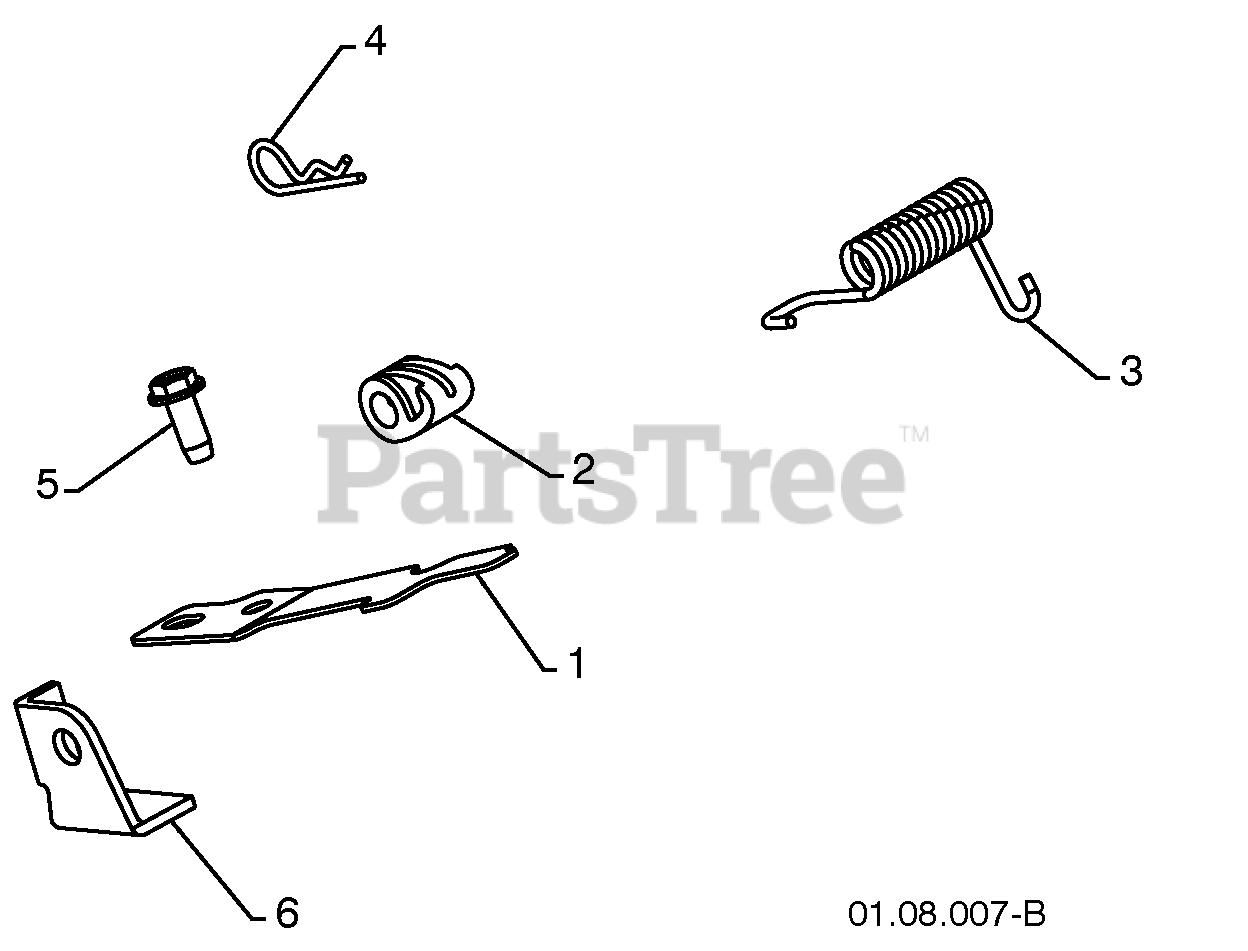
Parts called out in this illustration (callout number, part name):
1	INTERLOCK SPRING
2	INTERLOCK CAM
3	TORSION SPRING
4	RETAINER
5	SCREW 1/4-20 X .625
6	INTERLOCK STOP
